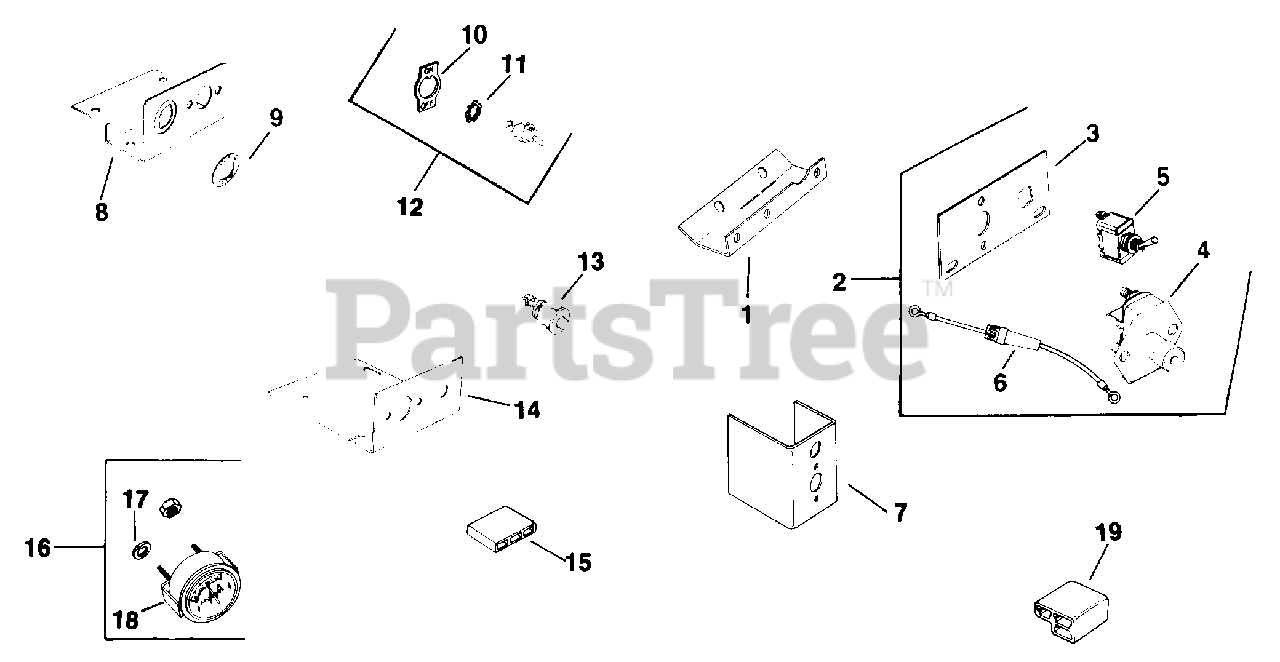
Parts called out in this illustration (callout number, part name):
4	SWITCH - DISCONTINUED
13	SWITCH - DISCONTINUED
16	KIT, AMMETER - DISCONTINUED
17	WASHER, SPRING LOCK #10
18	BRACKET - DISCONTINUED
